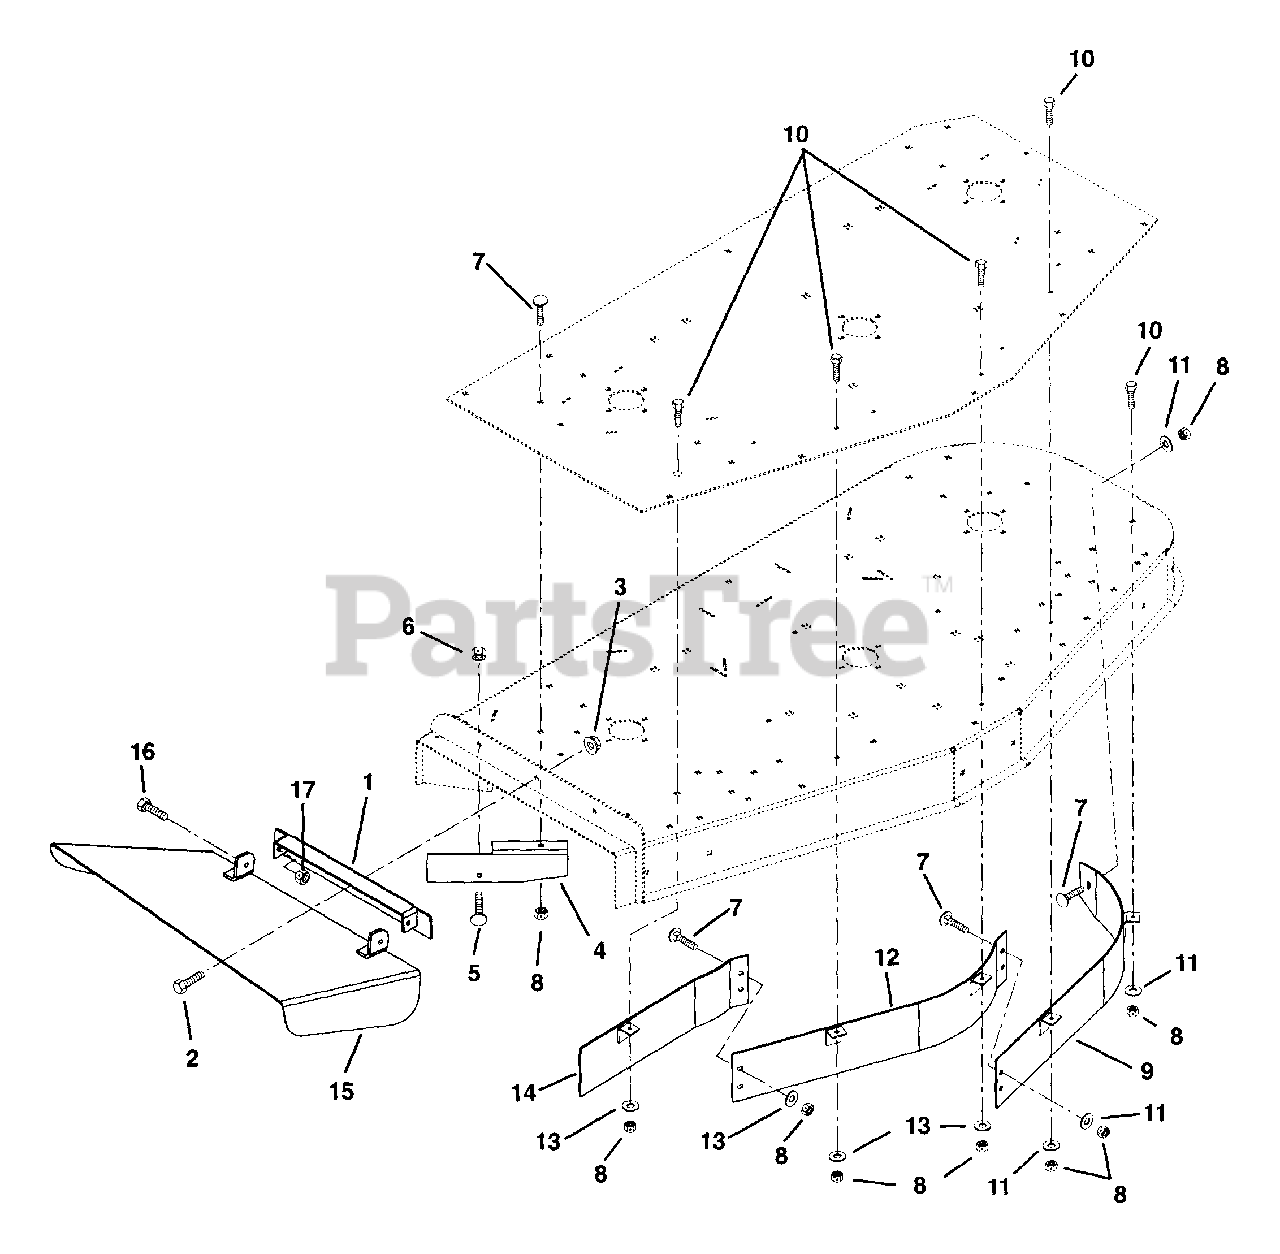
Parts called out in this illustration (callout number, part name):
1	Weldment, Discharge Chute Bracket
2	Bolt-Hex .38-16 x .75 Grade 5
3	Nut-Locking-Flange .38-16
4	Deflector, 60"
5	Bolt-Round Head Square Neck .38-16 x 1.00 Grade 2
6	Nut-Locking-Center .38-16
7	Bolt-Round Head Square Neck .31-18 x 1.00 Grade 5
8	Nut-Locking-Nylon .31-18
9	Weldment, 60" Left Hand Baffle-Upper
10	Bolt-Hex .31-18 x 1.00 Grade 5
11	Washer-Flat-Steel .312 x .734 x .065
12	Weldment, 60" Center Baffle-Up
13	Washer-Flat-Steel .312 x .734 x .065
14	Weldment, 60" Right Hand Baffle-Upper
15	Weldment, Discharge Chute 60"
16	Bolt-Hex .38-16 x 1.00 Grade 5
17	Nut-Locking-Center .38-16
